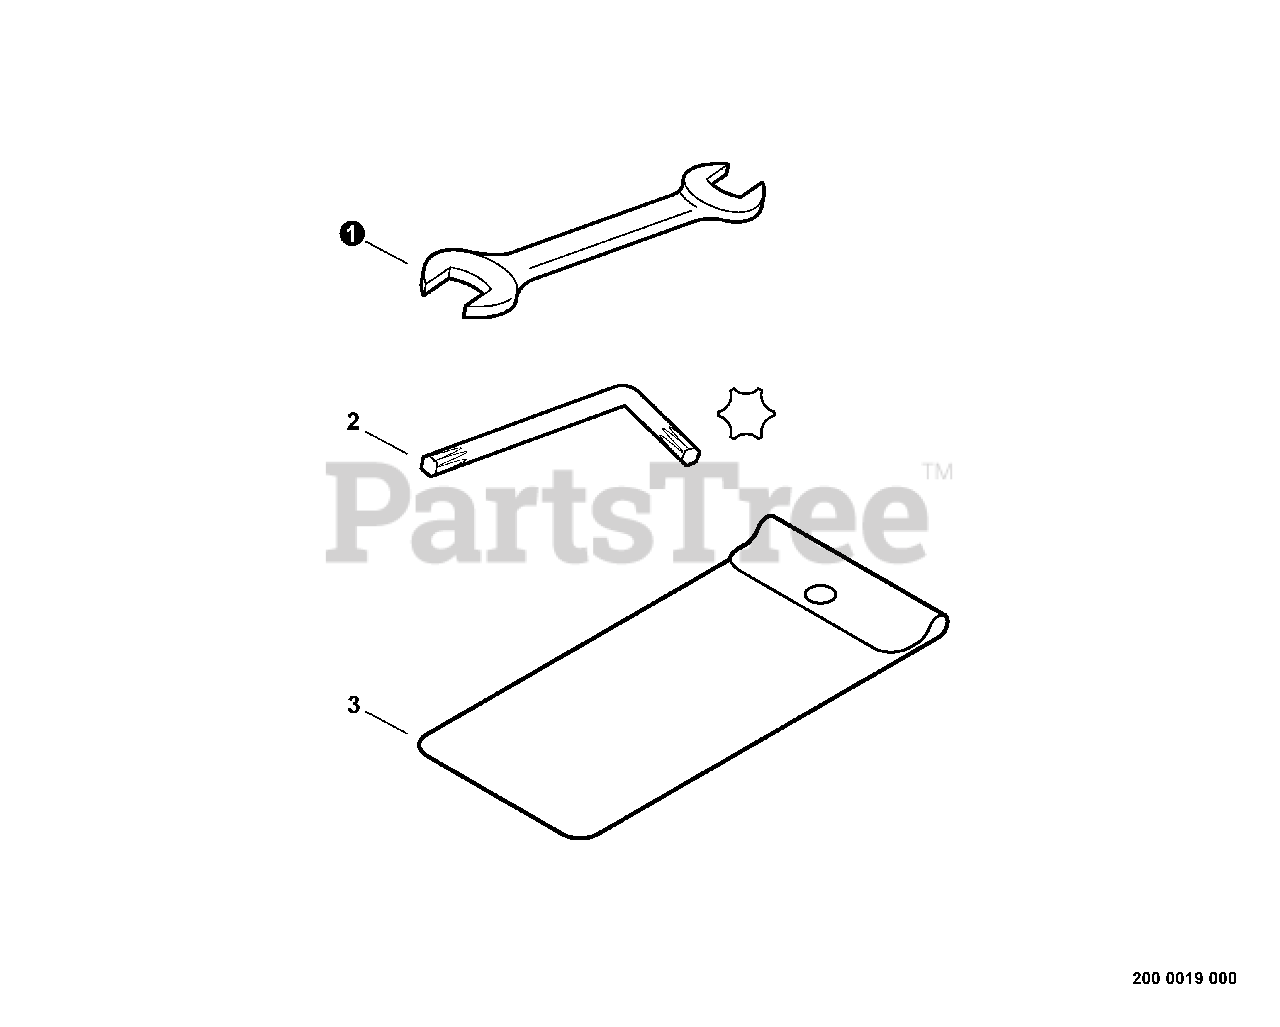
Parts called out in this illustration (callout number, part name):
1	SPANNER 8×10
2	WRENCH, T27 80×30
3	PIN - 2×22
